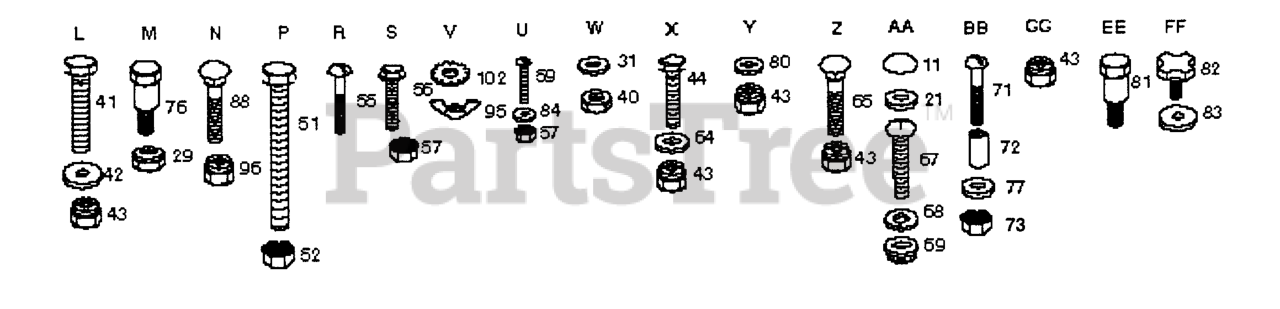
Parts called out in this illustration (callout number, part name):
11	SNAP CAP LT
29	LOCKNUT
31	WASHER PM
40	NUT
42	WASHER
44	BOLT
55	SCREW LT
56	BOLT.FIN.HEX.5/16-18X3/4
57	NUT
59	Screw, Truss Hd. 5/16-18 x 3/4
64	WASHER
65	Bolt, Carriage 3/8-16 x 3/4
67	SCREW
68	LOCKWASHER #10
69	WELDNUT
71	RP SCREW
73	NUT **
76	BOLT, SHOULDER LT
80	WASHER
81	BOLT,SHOULD
82	KNOB 1/2" YT
84	WASHER
88	Bolt Carriage 1/4 - 20 x 1-1/4
95	NUT.WING.LCK.NYL.NOTCH.1/4-20
96	NUT T
102	LOCKWASHER GT
